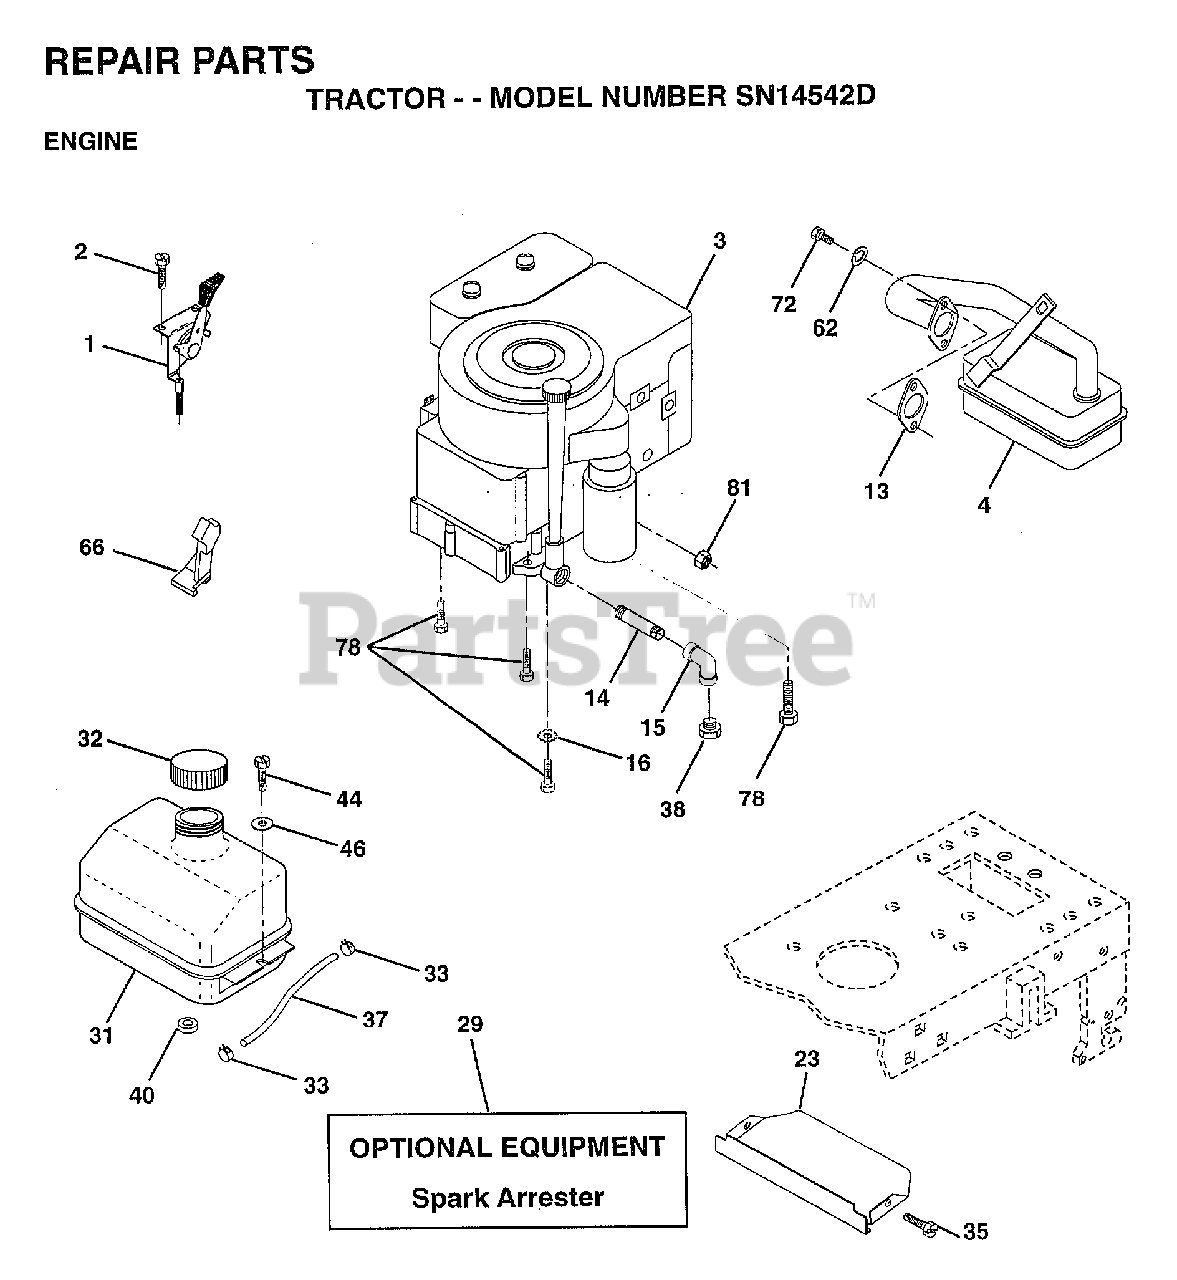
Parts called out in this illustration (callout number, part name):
1	CONTROL.THTL.23.5
2	SCREW LT
4	MUFFLER
14	PIPE NIPPLE
15	ELBOW
16	LOCKWASHER
23	SHIELD.BRN/DBR.GD
31	TANK.FUEL.LT.
32	CAP ASM FUEL
33	HOSE CLAMP
35	SCREW
37	LINE FUEL
44	SCREW HEX CRT
46	WASHER
62	LOCKWASHER
66	"STOP,DASH THROTT"
72	SCREW
78	SCREW
81	NUT
